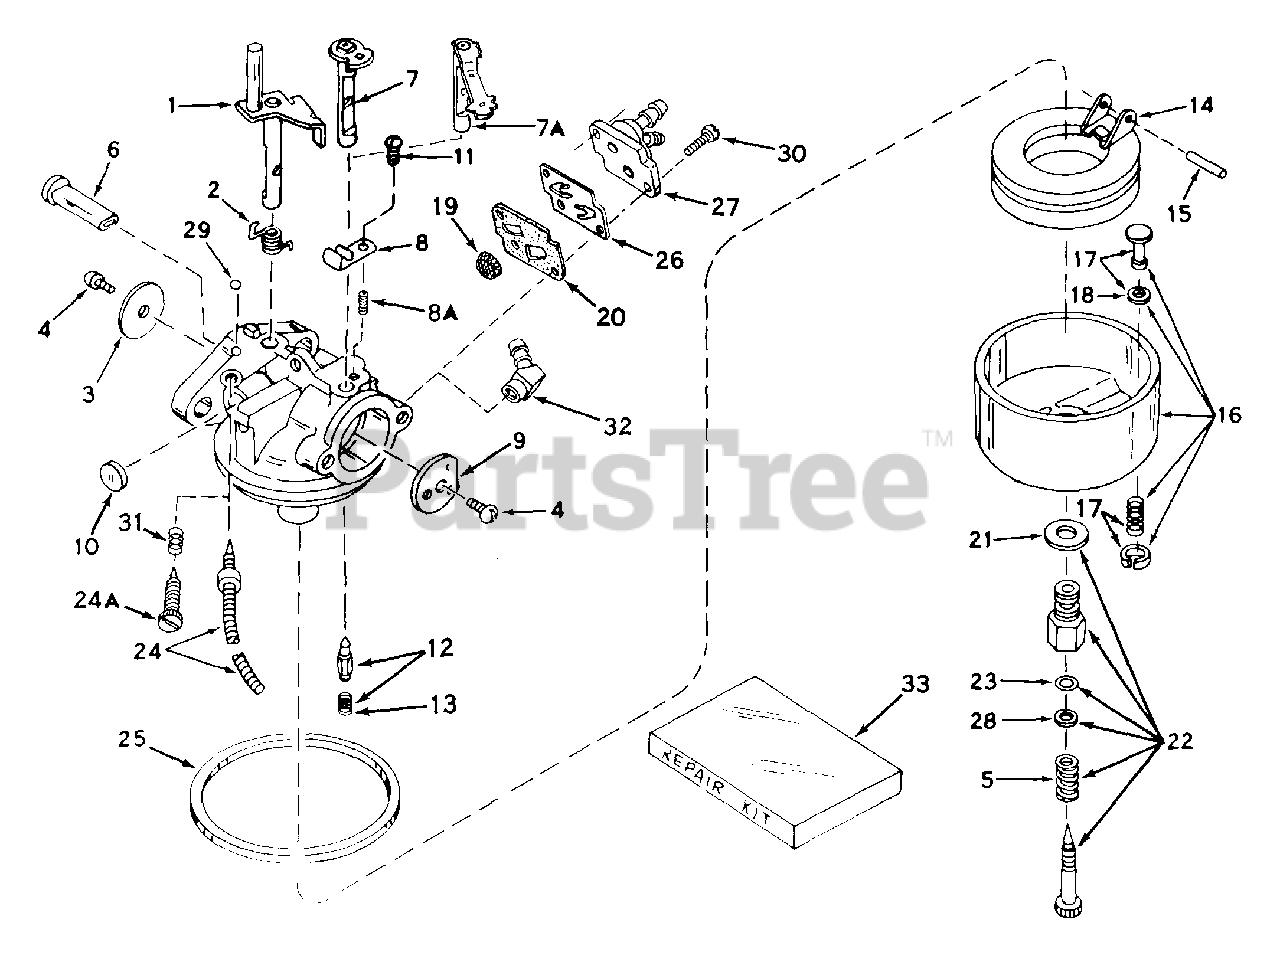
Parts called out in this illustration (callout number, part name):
1	"Shaft & Lever Assy., Throttle
2	Spring, Throttle return
3	Shutter, Throttle
4	Screw, Rd hd 4-40 3/16
5	Spring, Main adjustment screw
7A	Shaft & Lever Assy, Choke
8A	Spring, Positioning
9	Shutter, Choke
10	Plug, Welch
12	Inlet Needle & Spring Assy
13	Spring, Inlet needle
14	Float, Carburetor
15	Shaft, Float
16	Bowl & Drain Assy, Float
17	Plunger Assy, Drain
18	Gasket, Drain plunger
21	Gasket, Bowl-to-body
22	Adjustment Screw Assy,Main
23	"O" Ring, Adjustment screw
24A	Screw, Idle adjustment
25	Gasket, Bowl-to-body
29	Shot, Lead
31	Spring, Adjustment screw
32	Fitting, Fuel inlet
33	Repair Kit
